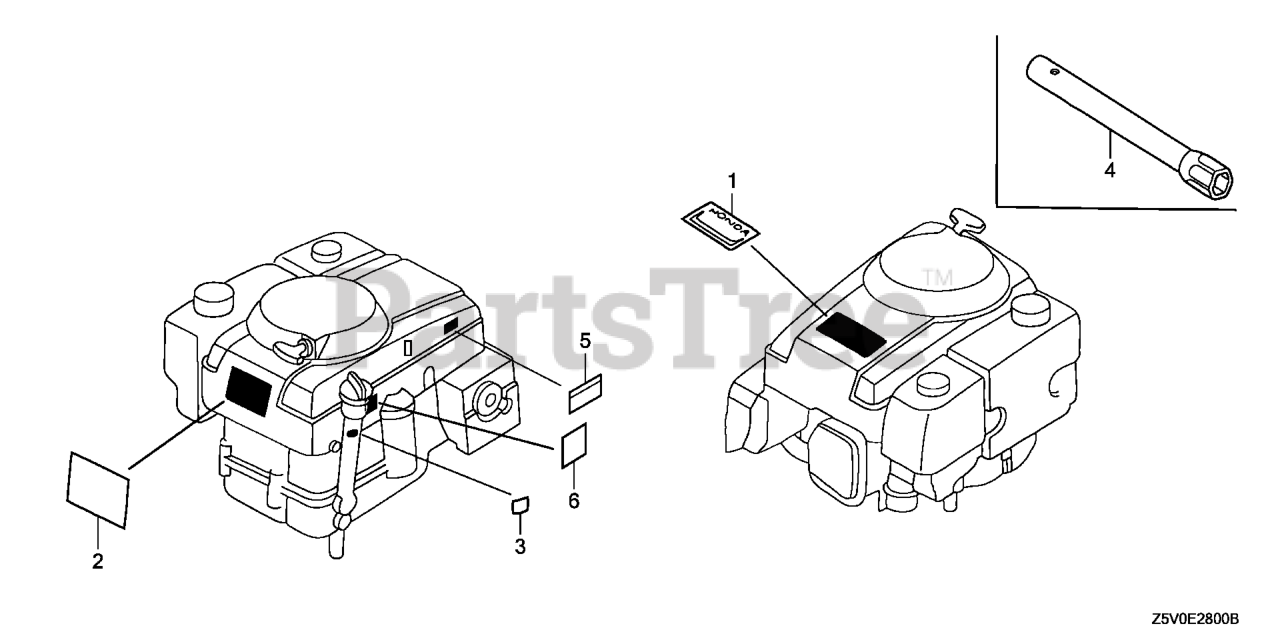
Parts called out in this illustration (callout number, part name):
1	EMBLEM, TOP COVER (GXV390)
3	MARK, TYPE (DAX4)
4	WRENCH, BOX (P21)
